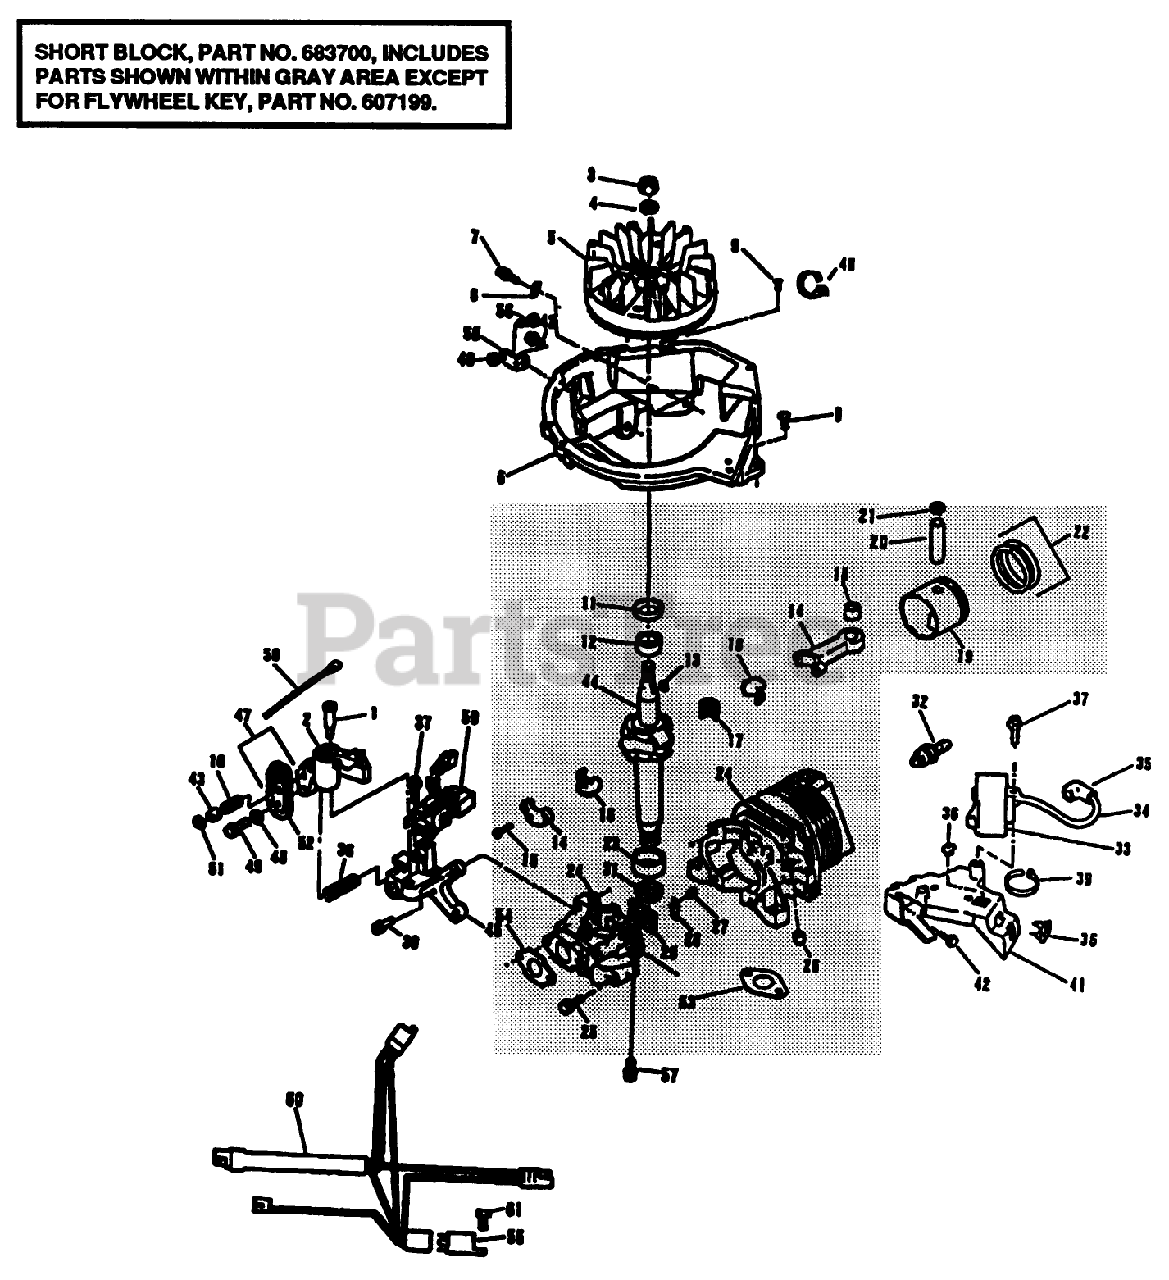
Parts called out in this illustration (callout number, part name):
1	SCREW-SHOULDER
3	NUT
5	FLYWHEEL ASSY F
6	BASE SHROUD F
7	SCREW-SEMS
9	SCREW F
10	SPRING
11	SEAL-OIL
12	BEARING V
13	KEY
15	SCREW-HSH
16	LINER ASM
17	BEARING-NEEDLE
18	BEARING AY F
21	RING-RETAINING
23	BEARING V
25	SCREW-H.W.HD. F
26	PLUG-CORE VF
27	SCREW-HH
28	PLATE-BACKUP, REED
30	SCREW
31	SEAL-OIL
32	SPARK PLUG
34	HT LEAD&COVER XEV
36	NUT-CLIP
38	SPRING-BRAKE
39	TIE-CABLE
40	NUT-LOCK F
41	BRACKET S
42	SCREW F
43	ACTUATOR-LEVER, BRAKE
45	BRACKET F
50	WIRE LEAD AY F
51	RETAINER S
54	GASKET CARB S
56	BOLT F
59	ALTERNATOR AY F
61	SCREW F
